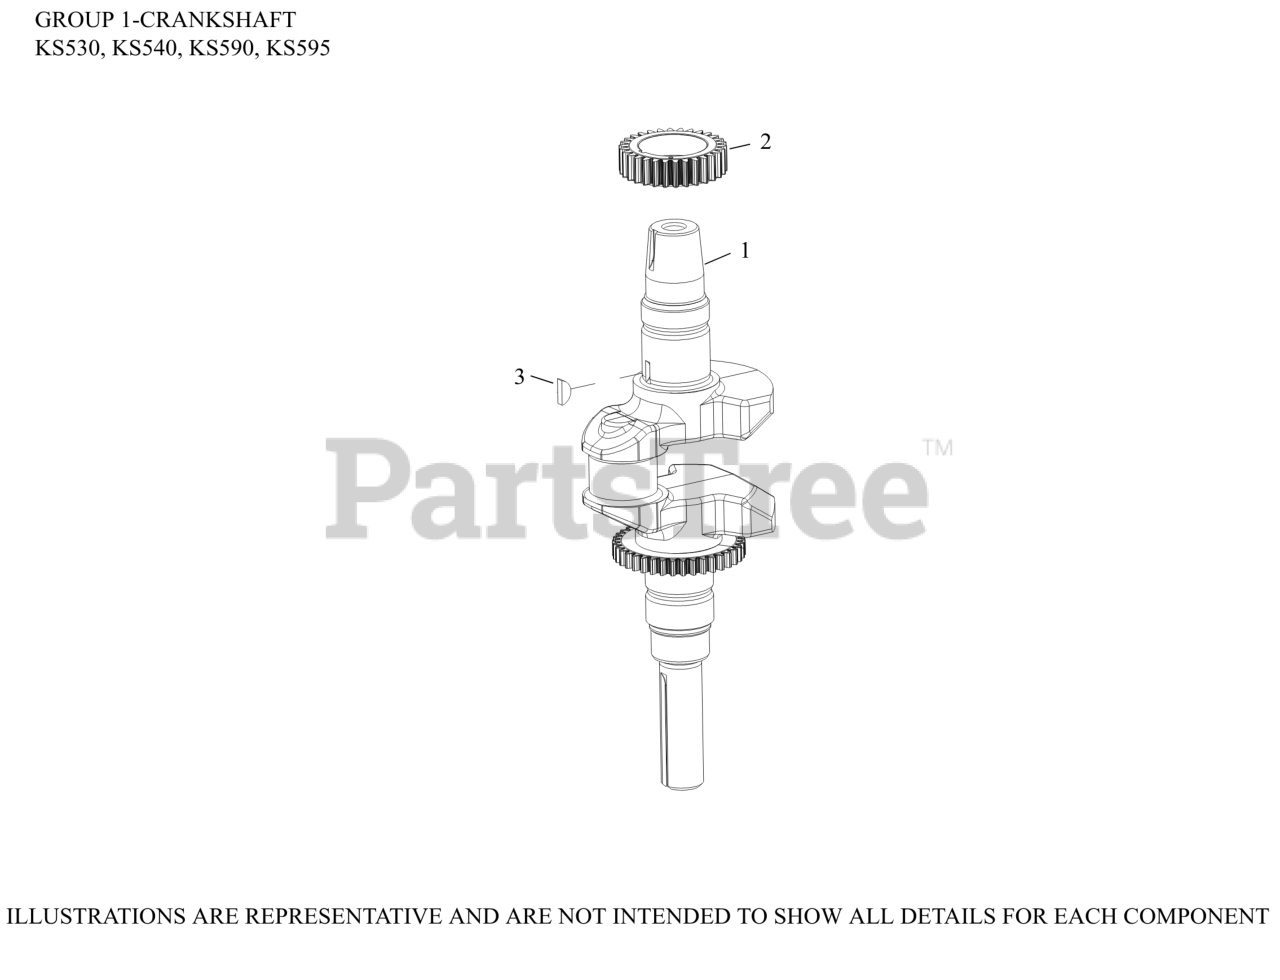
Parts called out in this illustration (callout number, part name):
1	CRANKSHAFT ASSEMBLY
2	GEAR, CRANKSHAFT
3	KEY, 3/16" X 5/8"
